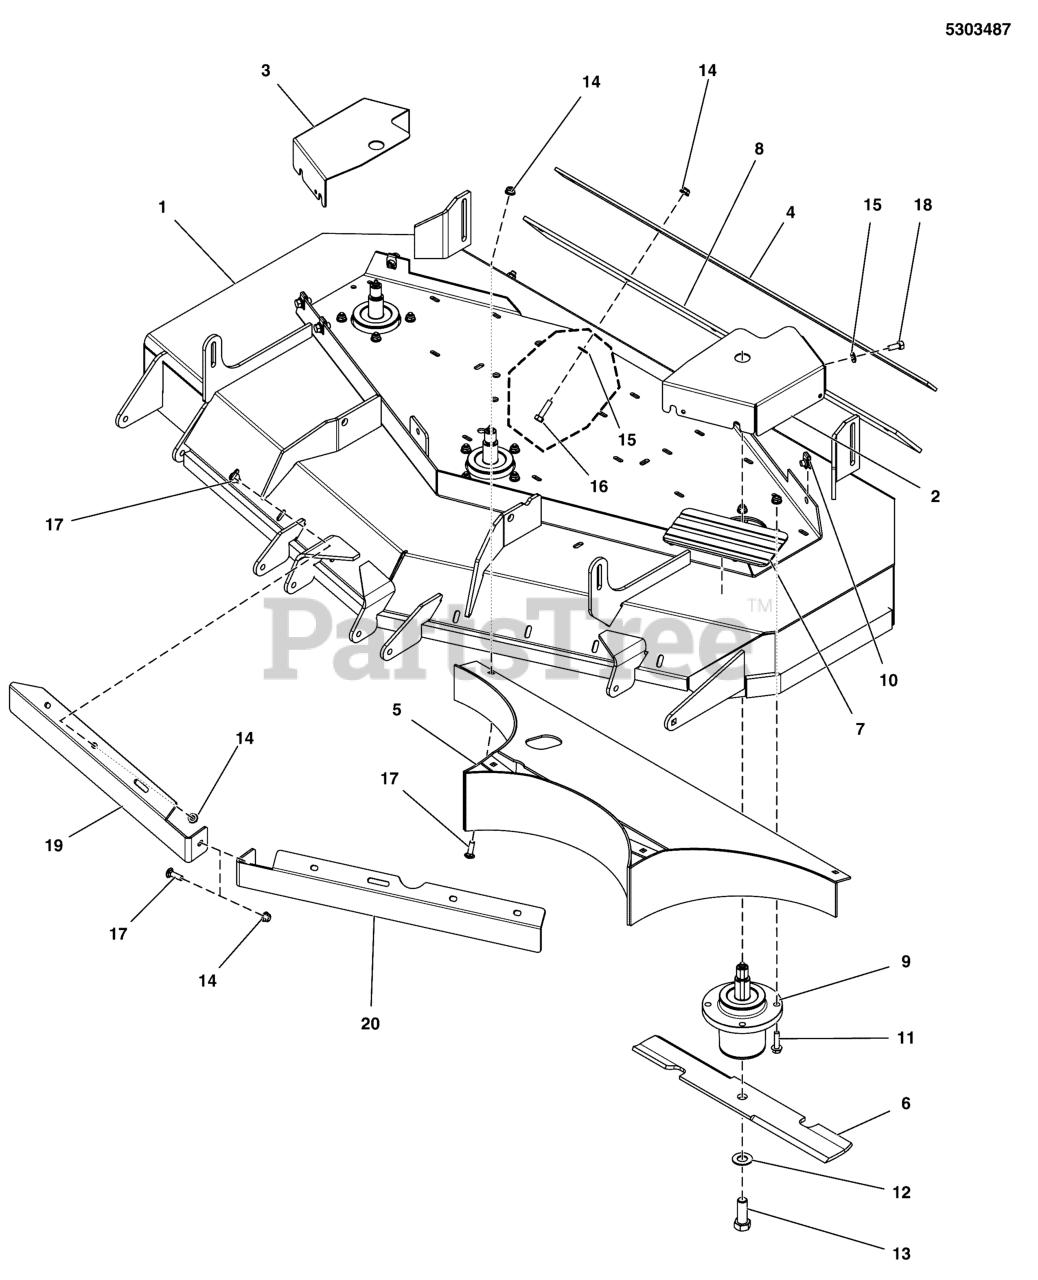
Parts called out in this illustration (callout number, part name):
1	DECK SHELL W/DECALS, 2500-52RDCE
1	DECK SHELL W/ DECALS, 52RDCE, IS2500Z
1	DECK SHELL W/ DECALS, 52RDANSI EXP, IS2500Z
2	GUARD, 52" DECK, IS2000 - LH - RED
3	GUARD, 52" DECK, IS2000 - RH - RED
4	PLATE, FLAP RETAINER, 2000 RD - BLK
5	WELD, REAR BAFFLE, 52 RD - BLK
6	BLADE, 18 X .25 X 2.5, 1 X 3.5 (SET OF 3)
7	SAFETY WALK, 4.00 X 7.50
8	FLAP, 2000 REAR DISCHARGE
9	ASSM, SPINDLE, LOW PROFILE
10	BODY CLIP, 5/16-18-7GA MATERIAL
11	BOLT, 5/16-18 X 1 1/4 FLANGE
12	WASHER, 5/8 GRADE 8, YZ
13	BOLT, 5/8-11 X 1-3/4 GD8
14	NUT, 5/16-18 HEX NYLOCK FLANGE
15	WASHER, 5/16" SAE
16	BOLT, 5/16-18 X 1-1/4 GD5 YZ
17	CARRIAGE BOLT 5/16-18 X 3/4
18	BOLT, 5/16-18 X 3/4 GD5
19	BAFFLE, FRONT DISCHARGE, LH, S150XCE - RED
20	BAFFLE, FRONT DISCHARGE, RH, S150X - RED
